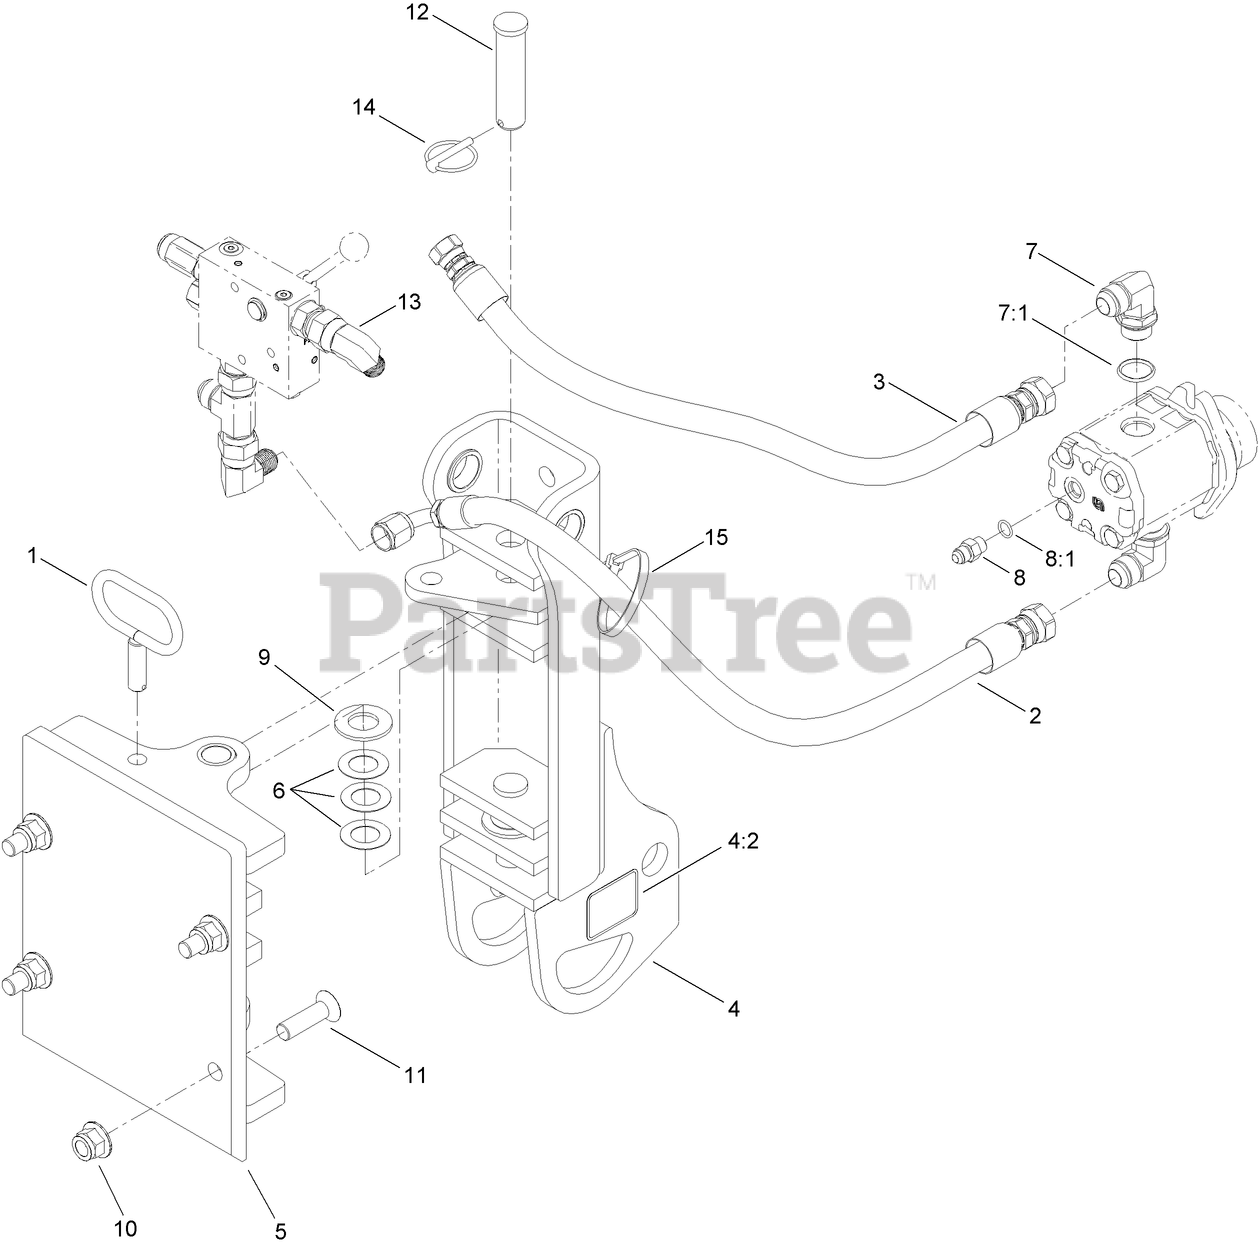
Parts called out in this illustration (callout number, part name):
1	LOCK-SWING
2	HOSE ASM
3	HOSE ASM
4	PIVOT ASM
4:2	DECAL-TIE DOWN
5	SLIDE-QUICK ATTACH
6	WASHER-FLAT
7	FITTING-ELBOW, 90 DEG
7:1	O-RING
8	FITTING-STRAIGHT
8:1	O-RING
9	WASHER-FLAT
10	NUT-HHF
11	SCREW-HSFH
12	PIN-PIVOT
13	FITTING-ELBOW, 90
14	PIN-KLIK
15	TIE-CABLE
